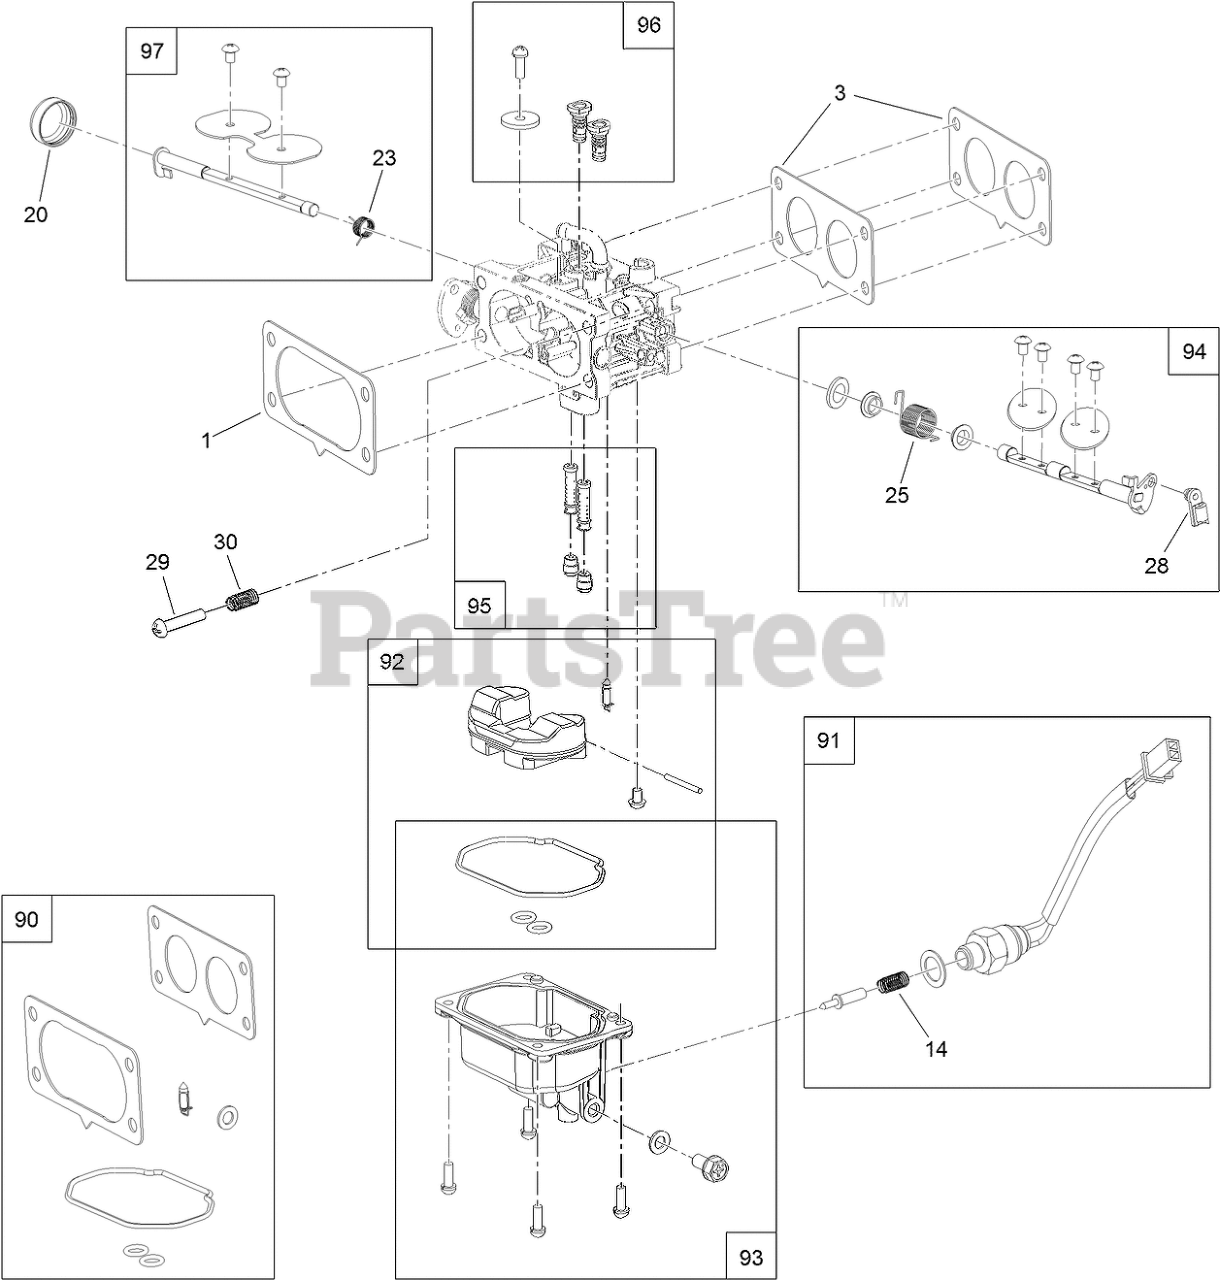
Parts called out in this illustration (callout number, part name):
1	GASKET-CARBURETOR
3	GASKET-CARBURETOR
14	SPRING
20	COVER-SHAFT, CHOKE
23	SPRING
25	SPRING
28	CLAMP-LOCK
29	SCREW-PPH
30	SPRING
90	CARBURETOR REPAIR KIT
91	SOLENOID KIT
92	FLOAT KIT
93	BOWL KIT
94	THROTTLE SHAFT KIT
95	NOZZLE AND JET KIT
96	IDLE JET KIT
97	CHOKE SHAFT KIT
